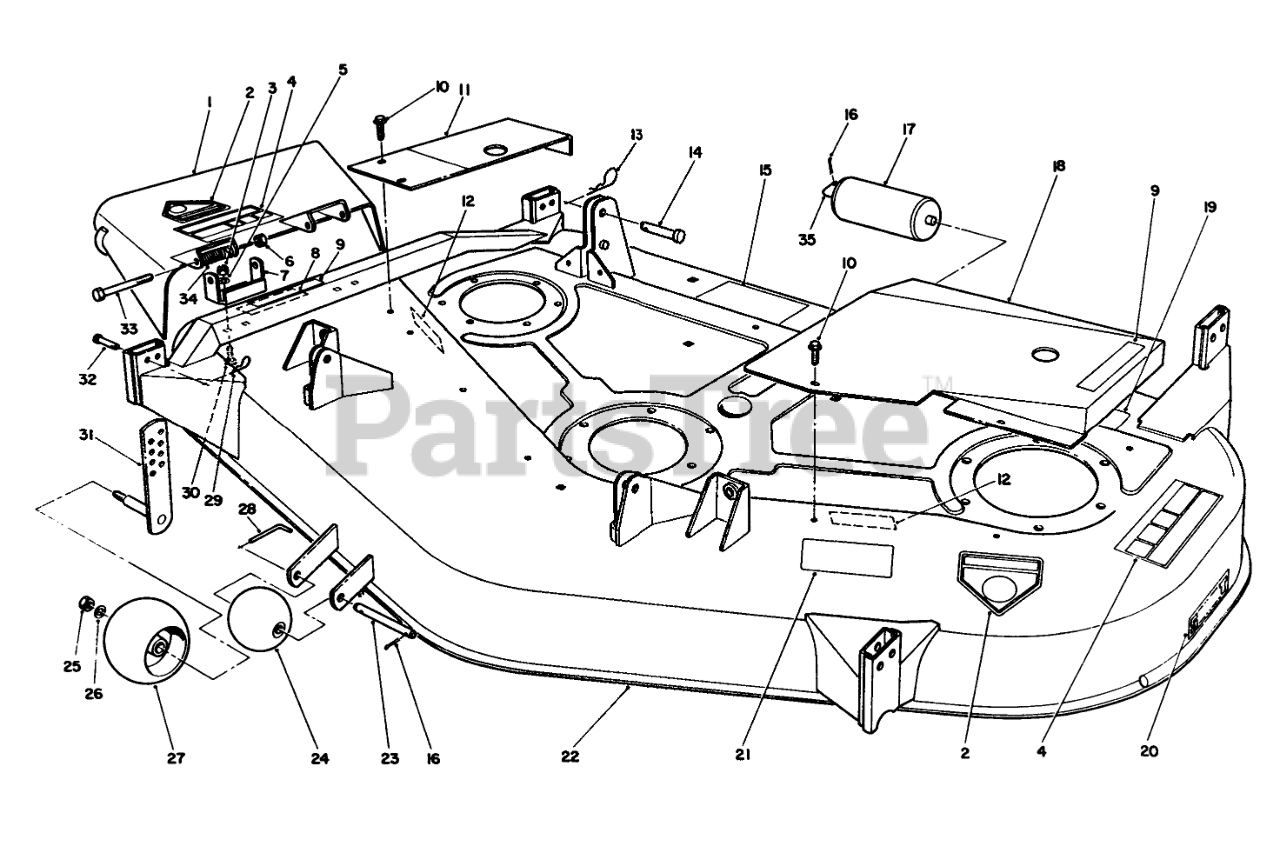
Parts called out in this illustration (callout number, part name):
1	Deflector Assembly (Incl. Ref. #2 & 4)
2	DECAL-DANGER
3	NUT-HEX
4	DECAL-DANGER, THROWN OBJECT
5	WASHER-LOCK
6	NUT-HEX
7	Bracket-Pivot
8	DECAL-DANGER
9	DECAL-NO STEP
10	SCREW-HHFTF
11	RIGHT COVER WA B
12	DECAL-DANGER
13	PIN-HAIR
14	PIN-CLEVIS
15	DECAL - BELT ROUTING
16	PIN-COTTER
17	ROLLER-DECK
18	LEFT COVER WA B
19	DECAL-TORQUE
20	DECAL - 52" CUT
21	DECAL - WHEEL ADJUSTMENT
22	Deck Ass-y-52"(Incl. Ref. #2,4,8,9,12,15,&19-21)
23	SHAFT-ROLLER
24	ROLLER
25	NUT-LOCK, NI
26	WASHER-FLAT
27	WHEEL-GAGE
28	PIN-SPECIAL
29	PIN-HAIR
30	SCREW-CARR
31	GAGE-WHEEL
32	PIN-CLEVIS
33	SCREW-HH
34	SPRING
35	SHAFT-ROLLER, REAR
